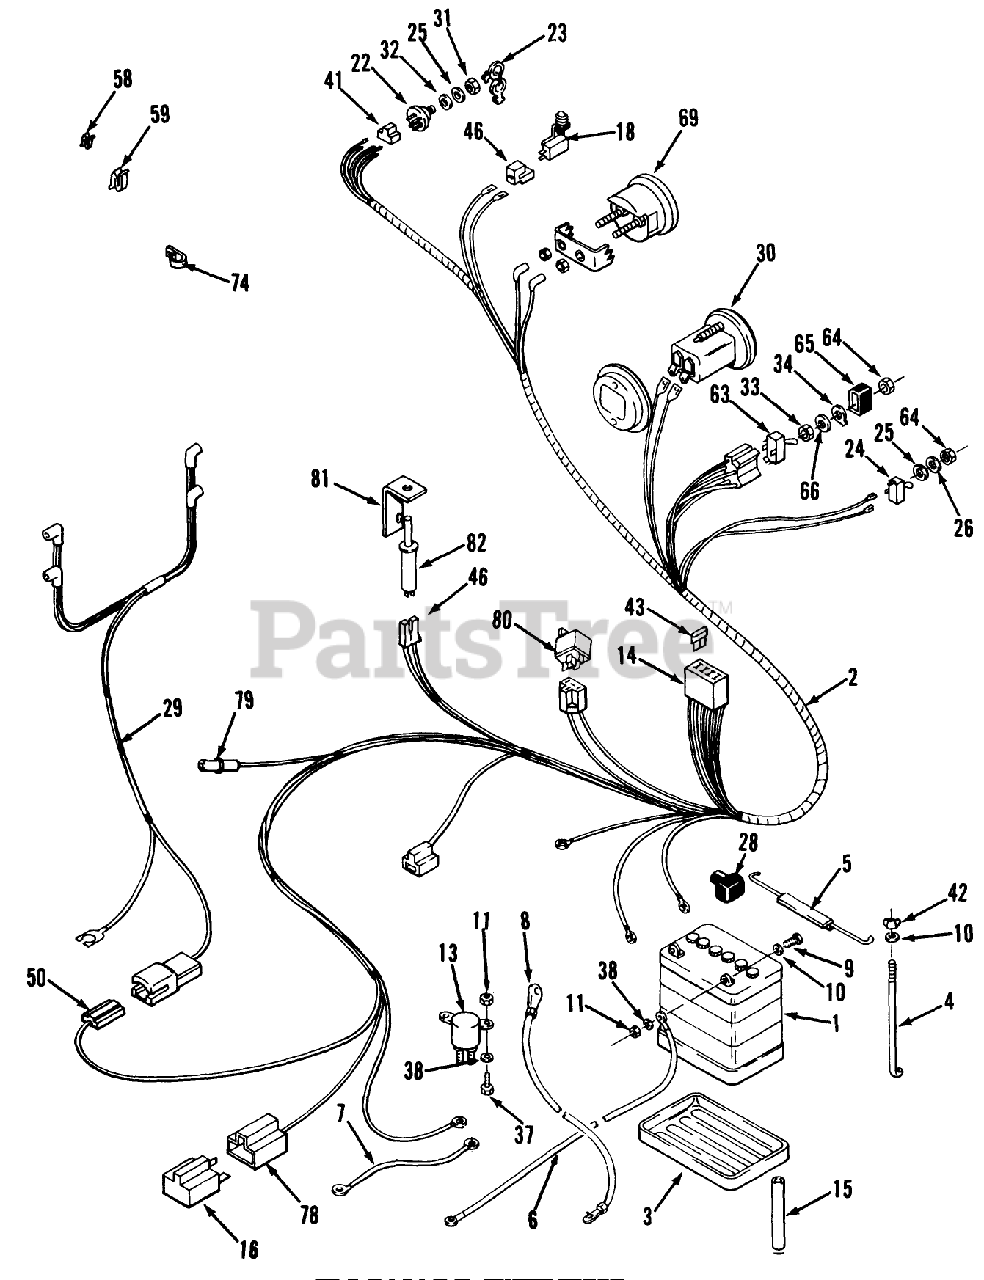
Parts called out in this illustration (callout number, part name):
3	TRAY-BATTERY
5	ROD-BATTERY HOLD DWN
6	WIRE - 14" BLACK
8	WIRE - 14" BLACK
15	TUBE-BATTERY DRAIN
22	KEY SWITCH ASM
24	SWITCH-LIGHTS
26	Washer
30	GAUGE-HOURMETER
34	TAB-WASHER
43	FUSE-BLADE, 15 AMP
46	CONNECTOR BODY
50	CONNECTOR BODY ELECT
58	CLIP
63	SWITCH-TOGGLE DPDT
64	*DISC**
65	COVER-PTO SWITCH
66	WASHER-FLAT
74	CLAMP
78	CONNECTOR 5 WAY
80	RELAY
82	SWITCH-PLUNGER
